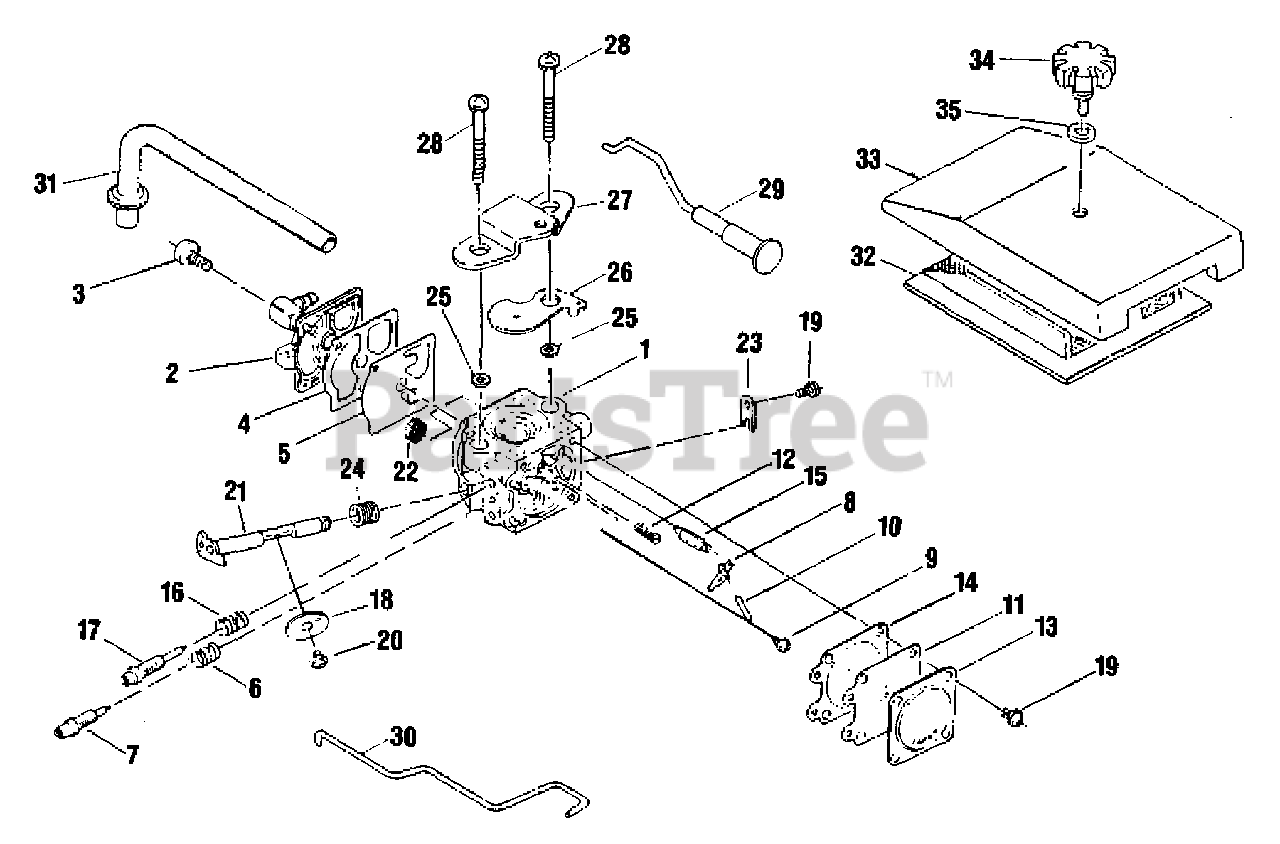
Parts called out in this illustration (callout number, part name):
1	CARBURETOR WA-115
2	PUMP COVER ASSY
3	SCREW, PUMP COVER
4	GASKET, PUMP
5	DIAPHRAGM, PUMP
6	SPRING
7	NEEDLE - LOW SPEED
8	LEVER, METERING
9	SCREW, METERING LEVER PIN
10	PIN, METERING LEVER
11	DIAPHRAGM, METERING
12	SPRING, METERING LEVER
13	COVER, DIAPHRAGM
14	GASKET, METERING
15	VALVE, INLET NEEDLE
16	SPRING
17	NEEDLE - HIGH SPEED
18	VALVE, THROTTLE
19	SCREW
20	SCREW
21	SHAFT
22	STRAINER
23	RING, RETAINING
24	SPRING, RETURN
25	WASHER
26	PLATE, SHUTTER
27	BRACKET
28	SCREW - 5X40
29	ROD, CHOKE
30	ROD, THROTTLE
31	PIPE - IMPULSE
32	FILTER, AIR - FLOCKED
33	AIR FILTER COVER ASSY
34	THUMBSCREW
35	O-RING
